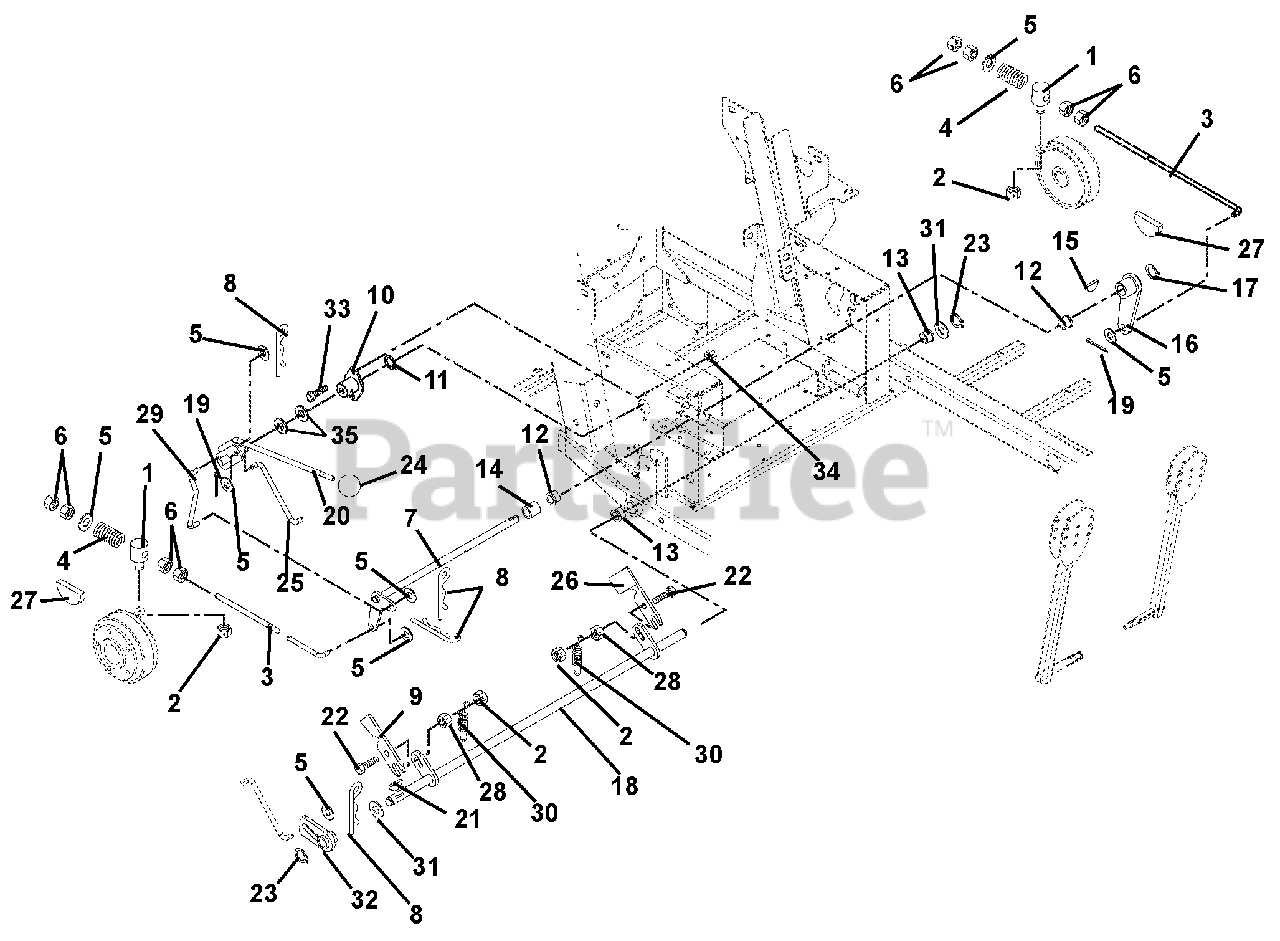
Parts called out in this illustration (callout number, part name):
1	Pivot, Brake Rod
2	Nut, Locking Center .31-18
3	PTO Link Rod
4	Spring, Compression .143 x .710 x 2.00
5	Washer, Flat Steel .406 x .812 x .065
6	Nut, Hex .38-16
7	Shaft, Brake Cross
8	Pin, Hair
9	Slide, Interlocking Brake
10	Bushing, Flange
11	Ring, Retaining External .625 x .05
12	Bushing, Flange Nylon .762 x 1.00 x .58 x 1.48
13	Bushing, Flange .515 x .75 x .745 x 1.00
14	Bushing, Sleeve .75 x 1.00 x .75
15	Key, Woodruff .19 x .75 Hard #9
16	Arm, Brake
17	Ring, Retaining External .69 x .077
18	Weldment, Mechanical Brake
19	Pin, Cotter External .09 x .75
20	Weldment, Brake Actuating
21	Key, Woodruff .13 x .63
22	Bolt, Hex .31-18 x 1.25 Grade 5
23	Ring, Retaining External .50 x .05
24	Knob, Steering Lock
25	Linkage, Brake Actuating
26	Interlock, Safety Switch
27	Pad, Disk Brake
28	Nut, Locking Top Flange .31-18
29	Linkage, Brake Actuating
30	Spring, Tension .048 x .44 x 1.75
31	Washer, Flat Steel .505 x 1.00 x .062
32	Weldment, Parking Brake Hub
33	Bolt, Hex .31-18 x .75 Grade 5
34	Nut, Locking Top Flange .31-18
35	Washer, Flat Steel .630 x 1.25 x .062
